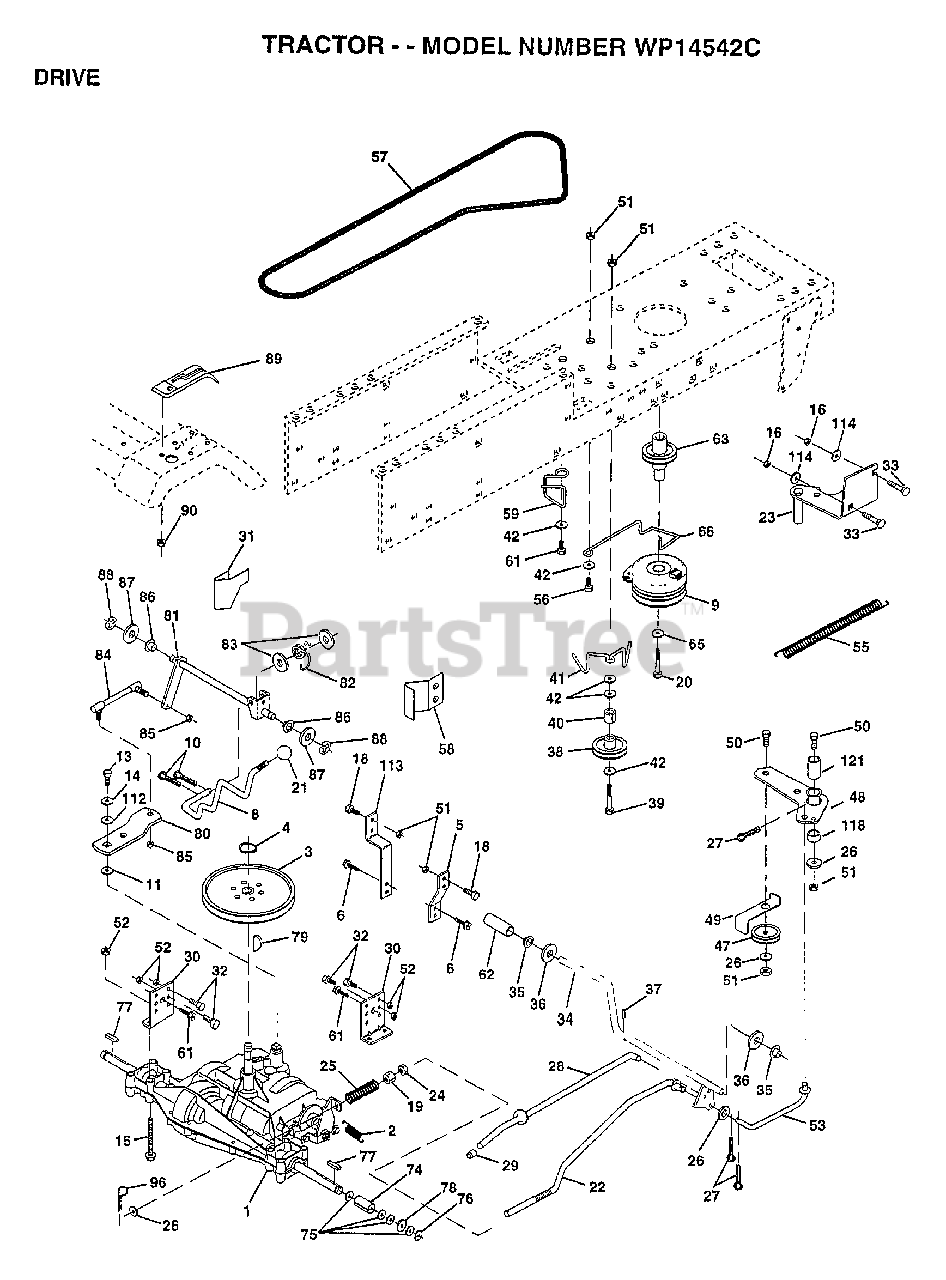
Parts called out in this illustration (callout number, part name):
1	TRANSAXLE PEERLESS
2	SPRING.BRAKE.RETU
3	PULLEY TRANS
4	STRAP TORQUE
6	SCREW
8	ROD SHIFT FEND YT
9	CLUTCH.ELECT.EVX.
10	PIN COTTER 1/8
11	WASH-SHFT PLT LT
13	BOLT.1/4-28.W/PAT
14	LOCKWASHER
15	BOLT.HX.FLG.5/16
16	NUT
18	BOLT
19	NUT
20	BOLT.7/16-20X4.25
21	KNOB T (1/2-HOLE)
22	BRAKE ROD
23	BRACKET.CLUT.MTG.
24	NUT
25	SPRING ROD LT
26	WASHER
27	COTTER PIN
28	ROD.BRAKE.PARK.LT
29	PLUNGER CAP T
30	TRANSAXLE MTG BKT
31	"KEEPER,BELT LH T"
32	BOLT
33	BOLT
34	SHAFT ASM-PEDAL F
35	NYLON BEARING
36	WASHER LT
38	PULLEY.IDLER.FLAT
39	BOLT
40	SPACER T
42	WASHER
48	BELLCRANK ASM
49	RETAIN BELT
53	"LINK, CLUTCH T"
55	"SPRING, RETURN LT"
58	"KEEPER,BELT RH T"
59	KEEPER BELT CNTSP
61	SCREW
62	PEDAL COVER T
63	PULLEY.CLUTCH.EVX
65	LOCKWASHER
66	KEEPER-BELT
74	SPACER AXLE
75	WASHER
76	E-RING LT
77	SQUARE KEY
78	WASHER
80	"ARM.SHIFT.20""TIRE"
82	"SPRING,TORSION"
83	WASHER
84	"ROD.TIE.20""P930LT"
85	NUT.CNT.LOCK.1/4
86	BUSHING
87	WASHER D
88	KLIP RING
89	CONSOLE SHIFT
90	NUT
112	WASHER LT
113	"STRAP,TORQUE"
114	WASHER
118	SPACER-BELLCRANK
121	NYLINER-CLUTCHING
